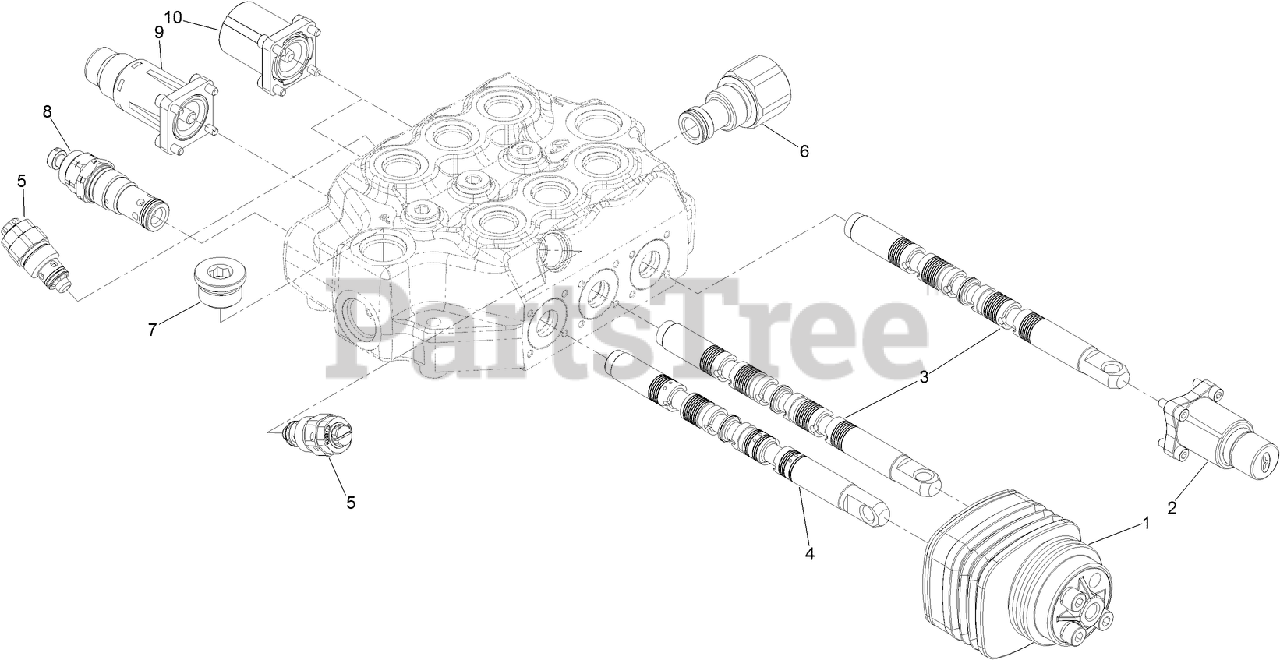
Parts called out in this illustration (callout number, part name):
1	KIT-COVER
2	KIT-END CAP
3	VALVE-SPOOL
4	VALVE-SPOOL
5	CARTRIDGE-RELIEF
6	JOINT-SAE12
7	PLUG-SAE12
8	KIT-VALVE
9	KIT-COMMAND
10	KIT-CONTROL
